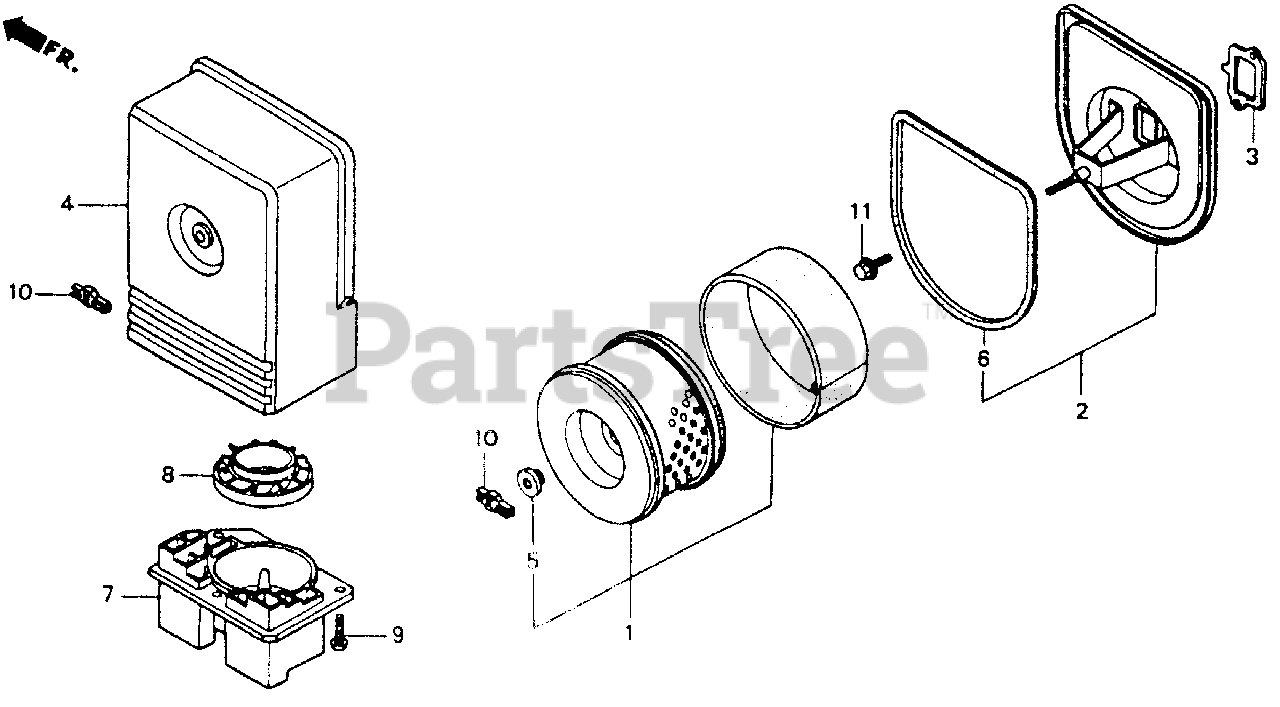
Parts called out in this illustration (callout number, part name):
1	ELEMENT, AIR CLEANER
2	HOUSING, AIR CLEANER
3	GASKET, AIR CLEANER
4	COVER, AIR CLEANER
5	GROMMET, AIR CLEANER
6	GASKET, AIR CLEANER HOUSING
7	CASE, PRE CLEANER
8	GUIDE, PRE AIR CLEANER
9	SCREW, PAN (5X16.5)
10	WINGNUT, AIR CLEANER COVER
11	BOLT, FLANGE (8X22)
